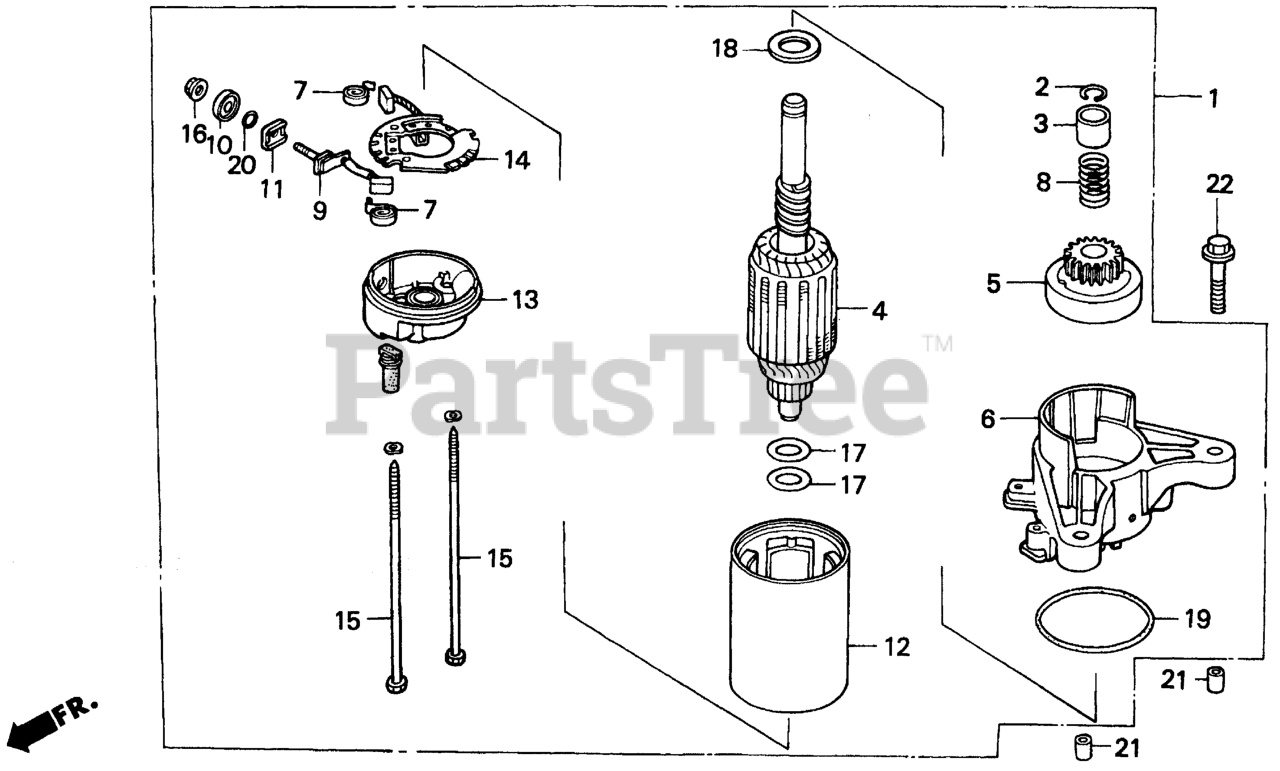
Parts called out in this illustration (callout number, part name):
1	MOTOR ASSY., STARTER
2	RING, SNAP
3	COLLAR, CLUTCH
4	ARMATURE
5	CLUTCH, OVERRUNNING
6	HOUSING, DRIVE SIDE
7	SPRING, BRUSH
8	SPRING
9	BRUSH
10	BUSHING, INSULATION
11	BUSHING, INSULATION
12	YOKE
13	FRAME, STARTER END
14	PLATE, BRUSH HOLDER
15	BOLT, THROUGH
16	NUT
17	WASHER
18	WASHER
20	O-RING
21	PIN A, DOWEL (10X16)
22	BOLT, FLANGE (8X35)
